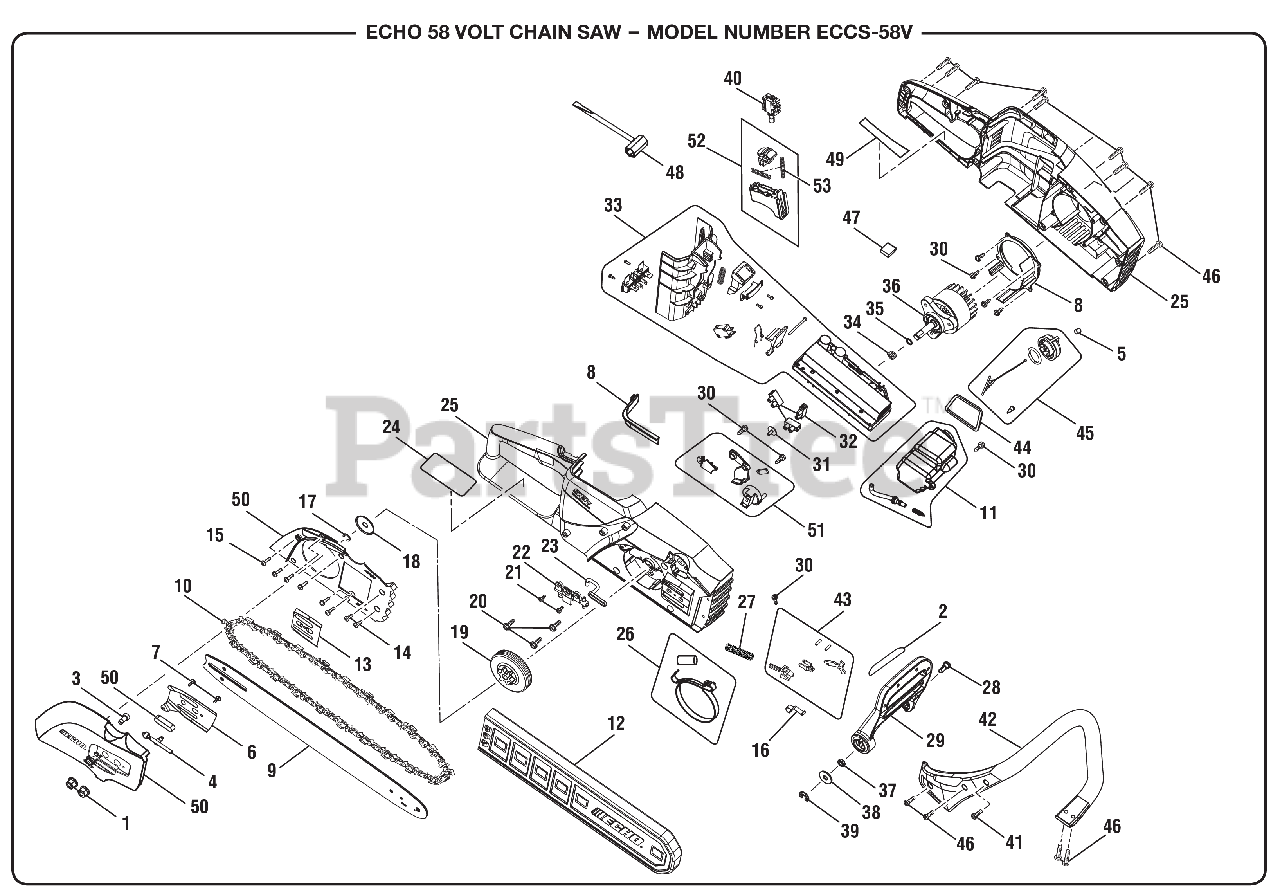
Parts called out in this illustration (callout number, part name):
1	Flange Nut (5/16-18, Hex Hd. for Guide Bar)
2	Chain Brake Label
3	Driving Adjustment Gear
4	Driven Adjustment Gear
5	Oil Cap Filter
6	Guide Plate
7	Screw (M4 x 12 mm, T20 Torx Hd.)
8	Volute & Wire Cover Assembly
9	Bar w/Graphics (16 in.)
10	Chain (16 in.)
11	Oil Tank Assembly
12	Scabbard (16 in.)
13	Guide Plate Bar
14	Screw (10-14 x 13 mm, T25 Torx Ch. Hd. )
15	Screw (M4-18 x 12 mm, T20 Torx Pan Hd.)
18	Cap Washer
19	Sprocket w/Drum
20	Screw (M5 x 15 mm, T25 Torx Flange Hd.)
21	Screw (M4 x 9.5 mm, T20 Torx Truss Hd.)
22	Oil Pump Assembly
23	Outlet Tube
24	Icon Label
25	Housing Assembly (Inc. Key Nos. 24 and 49)
26	Brake Bend Assembly
27	Chain Brake Spring
28	Screw (M5 x 10 mm, T25 Torx Hd. T.F.)
29	Front Handle Guard (Inc. Key No. 2)
30	Screw (M8 x 12 mm, T20 Torx Truss Hd.)
31	Screw (M4-18 x 10 mm, T20 Torx Washer Hd.)
32	TERMINAL
33	Battery Carriage and Circuit Board Assembly
34	Oil Pump Spring
36	Motor Assembly (Inc. Key Nos. 34-35)
37	Guard Bushing
38	Washer (ID6.8 x OD16 x 1.5t)
41	Screw (M5 x 25.5 mm, T25 Torx Rd. Hd.)
42	Front Handle
43	Brake bend Connector Assembly
44	Oil Tank Gasket
45	Oil Cap Assembly
46	Screw (M5 x 17.5 mm, T20 Torx Pan Hd.)
47	Wrench Spring Plate
49	Data Label
50	Side Cover Assembly
51	Chain Brake Assembly
52	Trigger Assembly
53	Compression Spring
